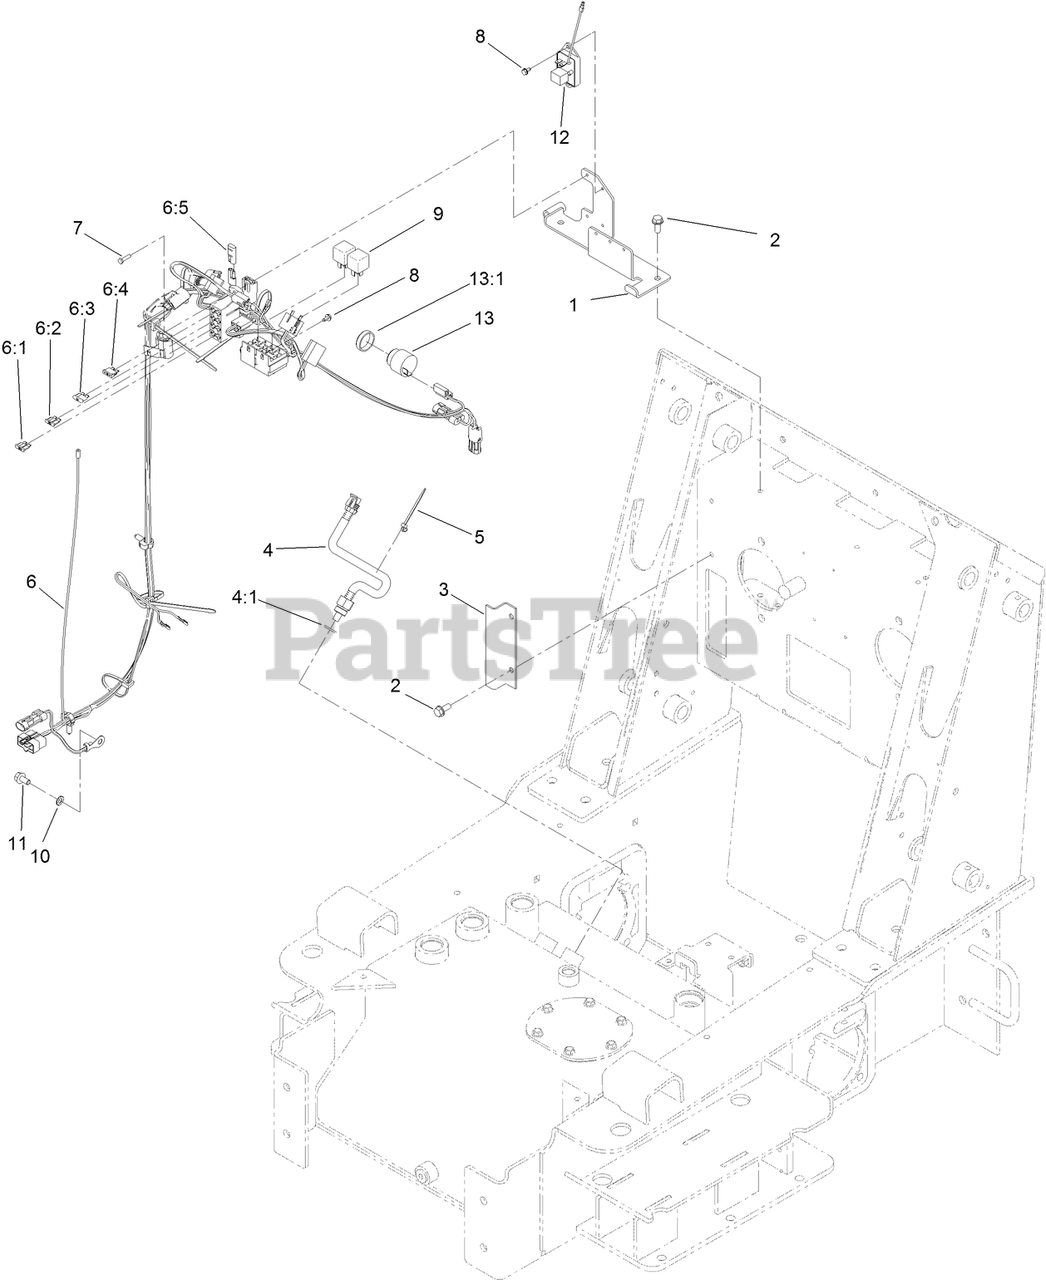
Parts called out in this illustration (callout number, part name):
1	BRACKET-FUSE/RELAY
2	SCREW-HWHTF
3	SHIELD-WIRING
4	SENSOR-TEMPERATURE
4:1	O-RING
5	TIE-CABLE
6	HARNESS-WIRE
6:1	FUSE-BLADE, 30 AMP
6:2	FUSE-BLADE, 25 AMP
6:3	FUSE-BLADE, 10 AMP
6:4	FUSE-BLADE, 15 AMP
6:5	CAP-PLUG
7	SCREW
8	SCREW-HWH
9	RELAY
10	WASHER-LOCK
11	SCREW-HHF
12	MODULE-IGNITION DELAY
13	AUDIO ALARM ASM
13:1	NUT-PLASTIC, KNURLED
